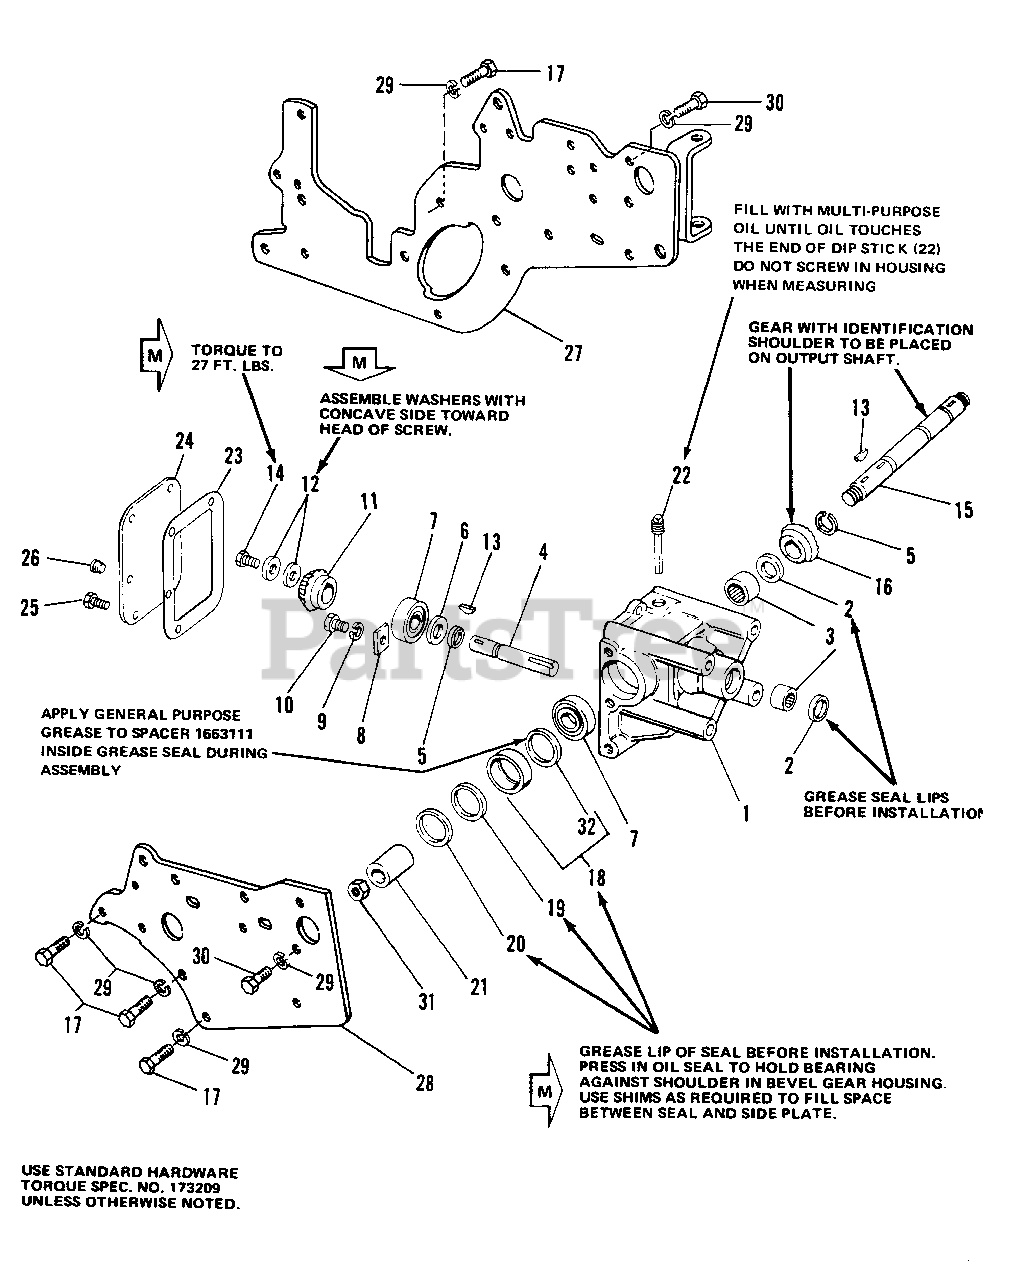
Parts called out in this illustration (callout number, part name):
1	HOUSING, Bevel Gear
3	BEARING, Needle
4	SHAFT, Driver
5	RING, Retaining
7	BEARING, Ball
8	PLATE, Bearing Clamp
9	LOCKWASHER, 5/16
10	CAPSCREW, Hex Hd., 5/16-18 x 5/8
11	GEAR, Bevel Driver
13	KEY, Woodruff, No. 9
14	CAPSCREW, Hex Hd., 5/16-18 x 3/4
15	SHAFT, Driven
16	GEAR, Bevel Driven
17	CAPSCREW, Hex Hd., 7/16-14 x 1-1/4
18	SEAL Oil, Kit, (Replaces 171787)
25	CAPSCREW, Hex, 1/4-20 x 5/8
27	PLATE ASSY, Side, L.H.
28	PLATE ASSY, Side, R.H.
29	LOCKWASHER, 7/16
30	CAPSCREW, Hex Hd., 7/16-14 x 1
31	LOCKNUT, Hex, Jam, 3/4-16
32	SPACER, Oil Seal
